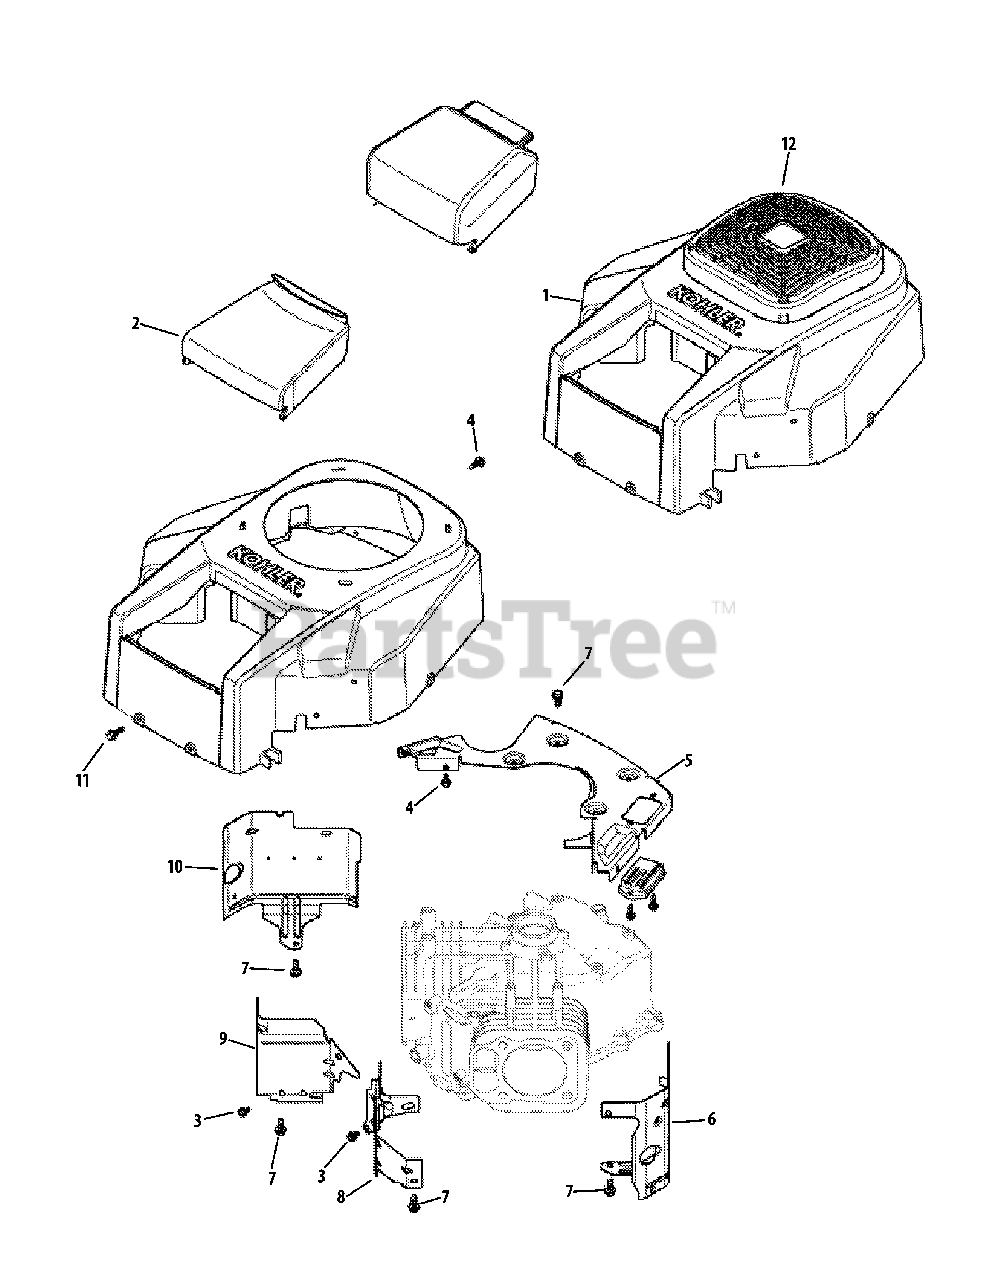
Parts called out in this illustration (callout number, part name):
1	Blower Housing Kit
2	Air Cleaner Cover
3	Flange Screw, M5 x .8 x 10
4	Flange Screw, M5 x .8 x 16
5	Backing Plate Kit
6	Cylinder Barrel Baffle, #2 Side
7	Flange Screw, M6 x 1.0 x 16
8	Valley Baffle, #2 Side
9	Valley Baffle, #1 Side
10	Cylinder Barrel Baffle, #1 Side
11	Screw, M6 x 1.7 x 18
